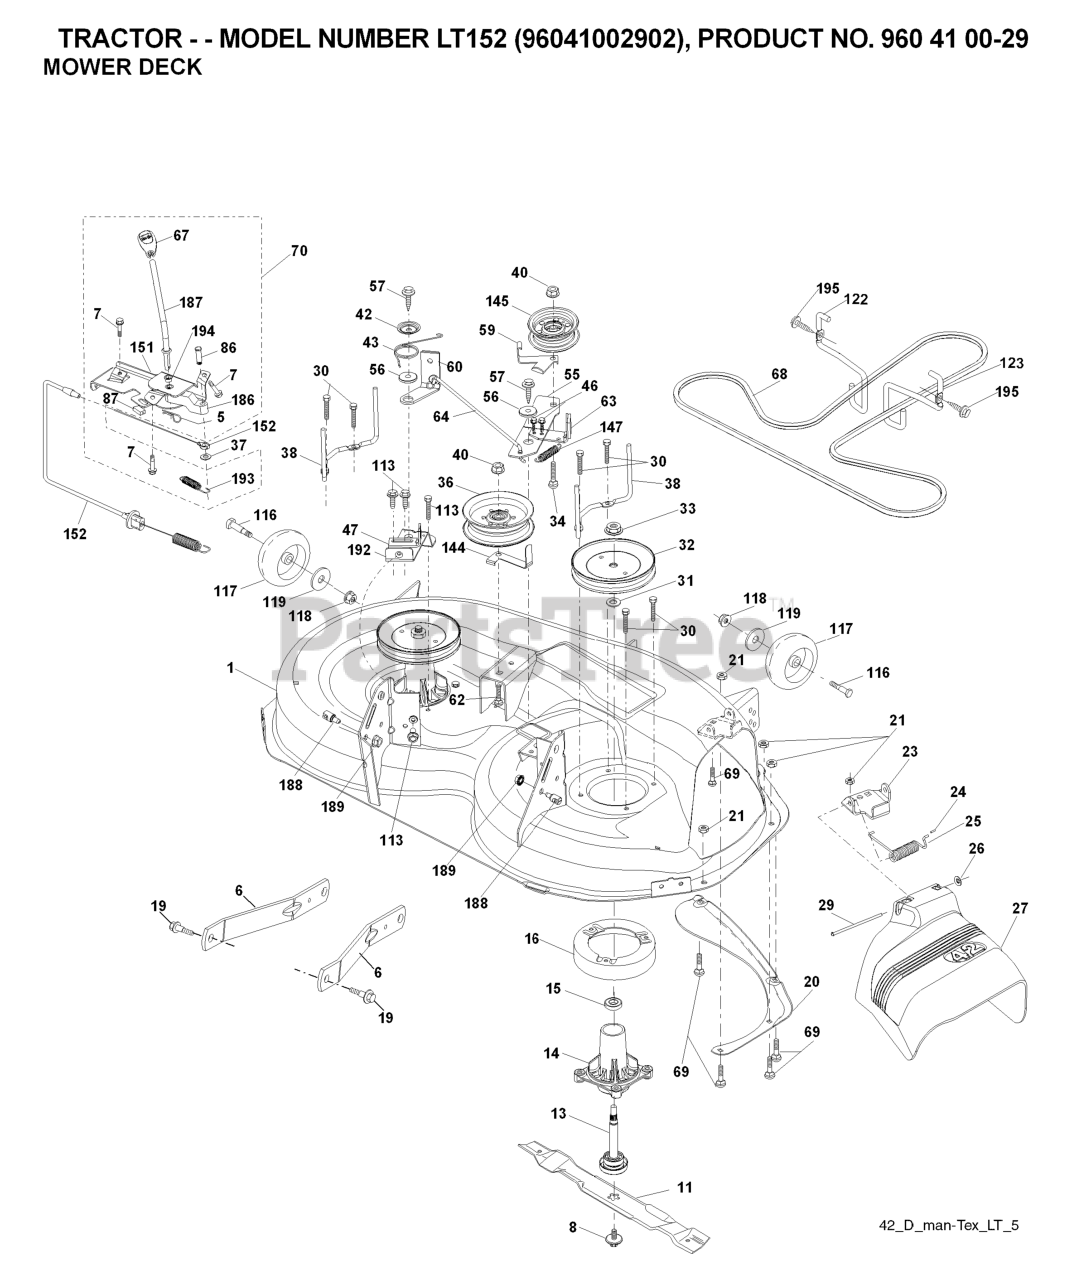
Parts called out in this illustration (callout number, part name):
1	DECK.WELDMENT.42"
5	RETAINER-SPRNG RB
6	ARM.SUSPENSION.MOWER.R
7	SCREW
8	BOLT.WASHER.ASM.7/16-2
11	42" HI-LIFT BLADE
13	SHAFT.ASM.MDRL.N/GREASE.38
14	RP.HOUSING.MANDREL.4PT.
16	STRIPPER.MANDREL.ROUND.BLACK
19	BOLT.SHOULDER
20	BAFFLE.VORTEX
21	LOCKNUT
23	BRKT.DEFLECTOR.38"2005+
24	CAP-SLEEVE LT
25	SPRING.TORSION.DEFLECT
26	NUT PUSH M
27	SHIELD.DEFLECTOR.MOWER.42"BLAC
29	ROD.HINGE
30	SCREW, WASHER HEAD
31	WASHER.SPACER.MANDREL
32	PULLEY.MANDREL.5.438.PD
33	NUT.FLANGE.LOCK.TOP
34	BOLT.3/8-16X1.50
36	PULLEY.IDLER.48"PRIMARY
37	WASHER
38	KEEPER.BELT.LH.MANDREL
40	NUT LOCK FLG 3/8-16 UNC
42	SPRING.TORSION.BRAKE
43	SRPING.TORSION.RETAINE
46	SCREW.1/4-20X5/8
47	BRKT.CLUTCH.CABLE
56	SPACER.RETAINER
57	SCREW 3/8-16X1
59	GUARD, BELT
60	ARM BRAKE MOWER
63	ARM BRAKE MOWER
64	LINK BRAKE
67	HANDLE.CLUTCH.CABLE.LT
68	BELT.DRIVE.MOWER.TEX.42"
69	BOLT
70	CLUTCH.ASM.MANUAL.LT.PRED
86	PIN ATTACHMENT CABLE
87	SWITCH.INTRLCK.CLUTCH.
113	BOLT.5/16HEX.WHS.HD
116	BOLT M
117	WHEEL.GAGE.HALF.SPOKED
118	LOCKNUT
119	WASHER.5/16.FLAT.STE.STD.
122	KEEPER BELT ENGINE LH
123	KEEPER BELT RH
144	KEEPER.BELT.MOWER
145	PULLEY.IDLER.2006
147	RETURN SPRING
151	BRACKET.CLUTCH CBL.PRED LT
152	CLUTCH CABLE
186	ARM ACTUATOR
187	LEVER.CONTROL.CL.CABLE.PRED LT
188	STUD.FASTNER.W/ANTI-ROTATE
189	NUT LOCK HEX FLANGE 5/16-18
192	BRKT.BRAKE.STAND.LH.
193	SPRING.PLUNGER.ACTUATOR
194	BEARING.CONTROL.LEVER.CLUTCH
195	SCREW, 3/8-16X3/4
